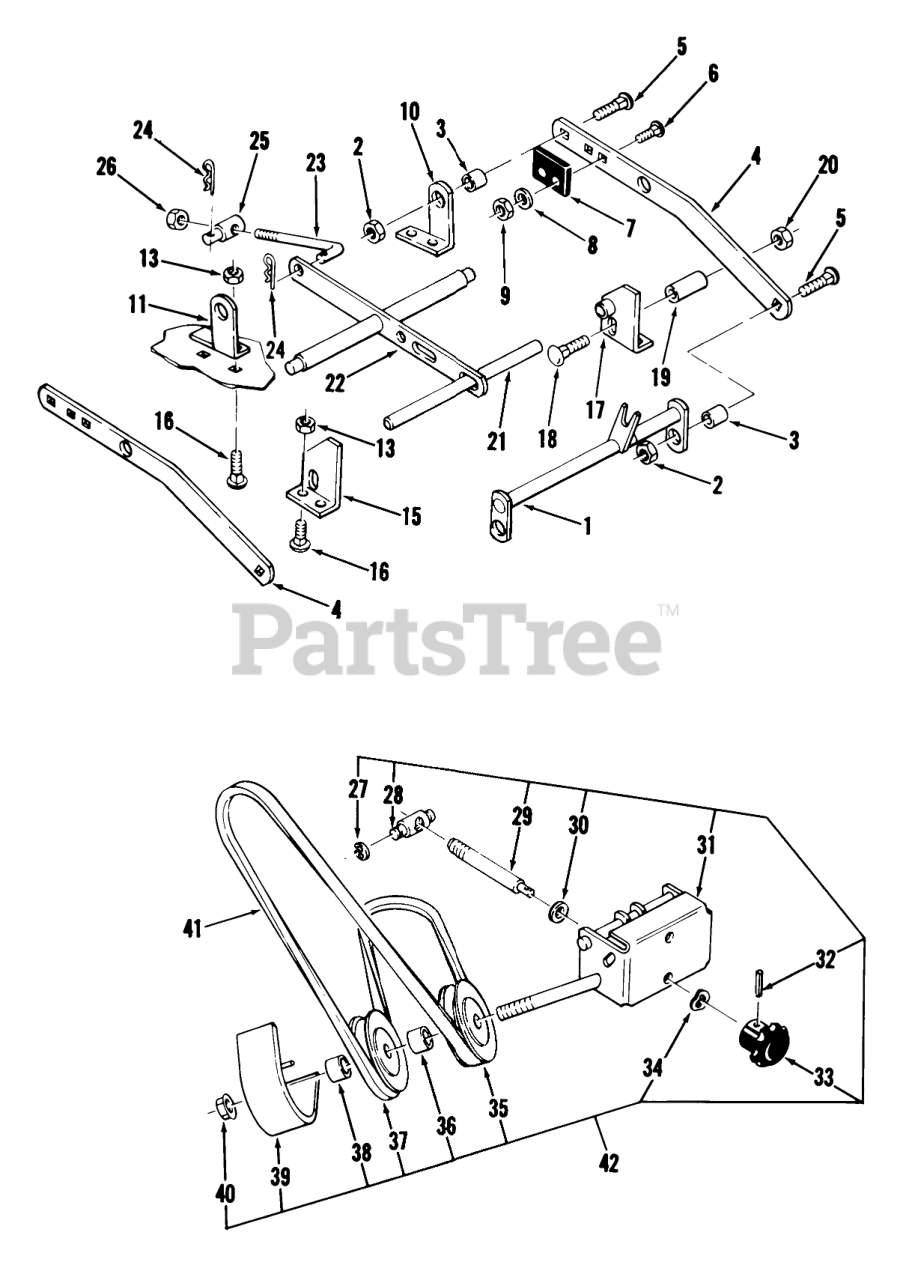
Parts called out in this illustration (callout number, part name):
1	Hitch
2	LOCKNUT-FLANGE
3	SPACER
4	Bar Draft
5	Bolt
6	Bolt-Carriage
7	BUMPER
8	Collar
9	Nut
10	LH Rear Bracket
11	Rear Bracket RH
13	Nut
15	Front Bracket RH
16	Bolt-Carriage
17	Front Bracket LH
18	CARRIAGE BOLT -4
19	SPACER-BEARING
20	Nut
21	Front Shaft
22	Leveler
23	ROD-LEVEL ADJUST
24	Hairpin
25	TRUNNION-LIFT
26	NUT
27	RING-RETAINING
28	TRUNNION-DOUBLE
29	ROD ADJ
30	Washer
31	Front Support
32	PIN-ROLL
33	KNOB-ADJUSTMENT
34	Spring Washer
35	Pulley-V
36	SPACER
37	PULLEY-FLAT IDLER
38	SPACER-OUTER
39	Belt Cover
40	Nut 3/4-16 MF
41	V-BELT
42	ASM-SUPPORT,IDLER
